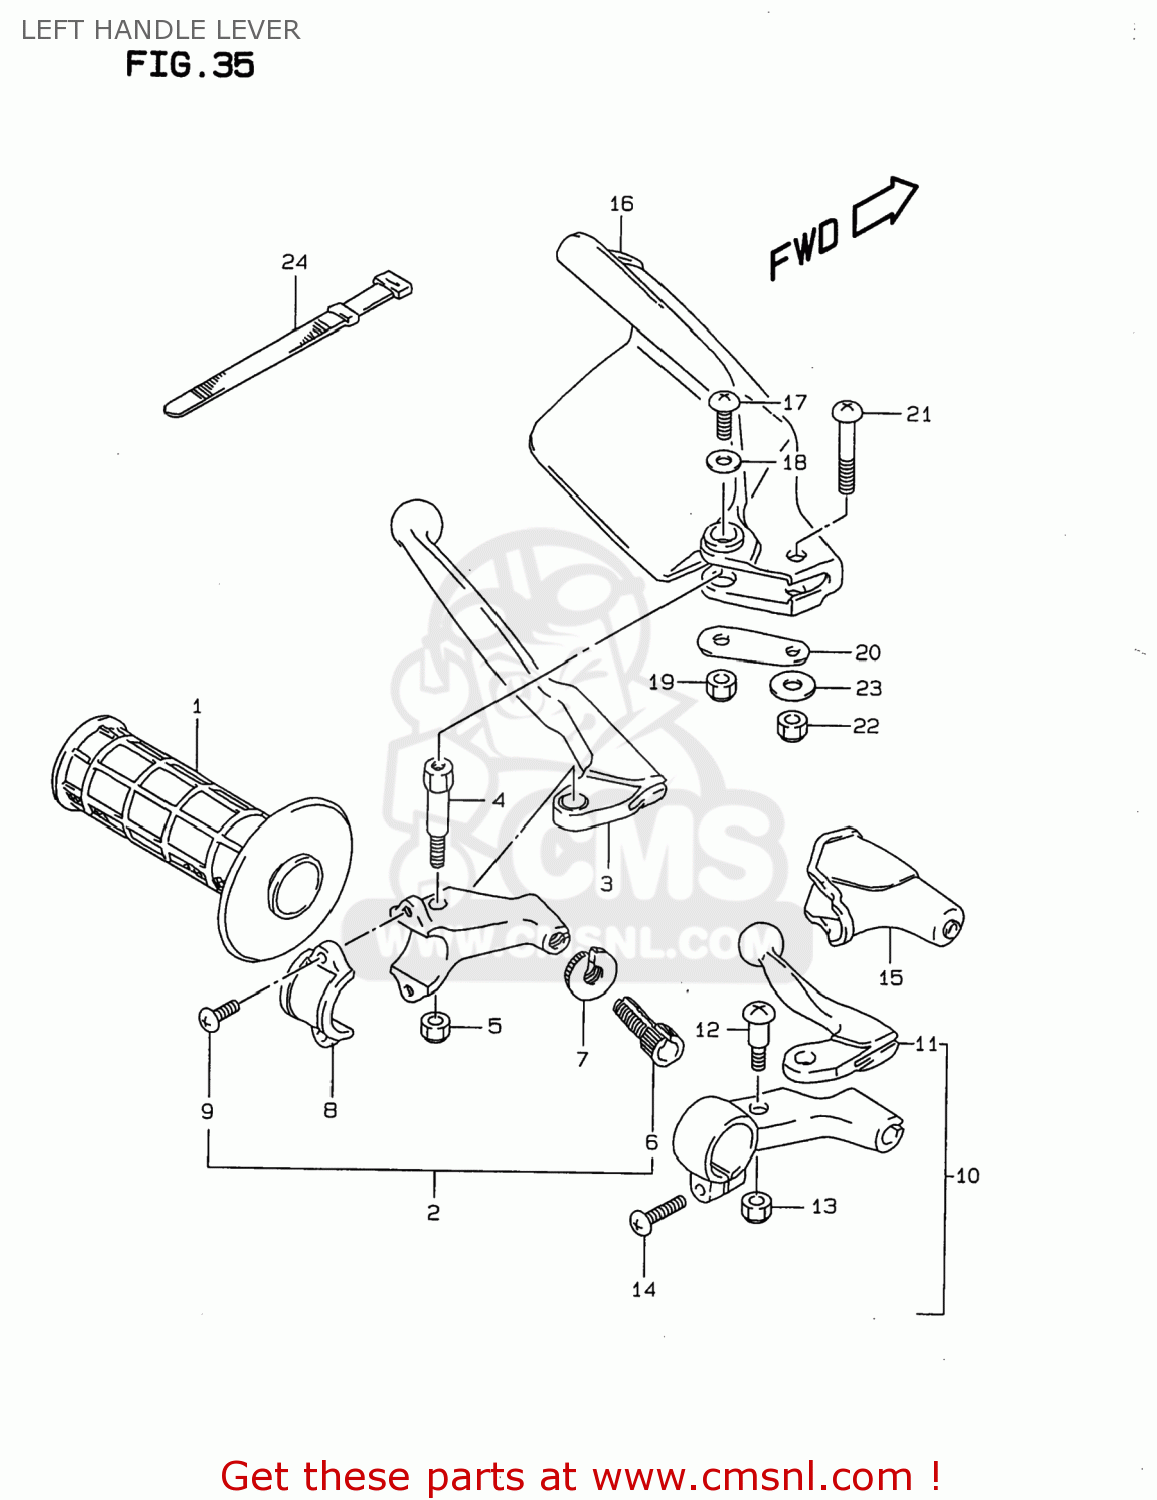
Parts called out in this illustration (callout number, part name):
1	GRIP,L
2	LEVER ASSY,CLUTCH
3	LEVER,CLUTCH
4	BOLT,LEVER SET
5	NUT 6MM
6	ADJUSTER,CABLE
7	NUT,LOCK
8	BRACKET,CLUTCH LEVER HOLDER
9	SCREW(5X14)
10	LEVER ASSEMBLY,DECOMPRESSION
11	LEVER,DECOMP
12	BOLT,LEVER PIVOT
13	NUT
14	SCREW, 6X20
15	COVER,DECOMP LEVER DUST
16	COVER,KNUCKLE,L
17	SCREW
18	WASHER(5.5X16X1.2)
19	NUT 6MM
20	PLATE,KNUCKLE COVER,L LWR
21	SCREW(6X35)
22	NUT 6MM
23	WASHER(6.5X16X1.6)
24	CLAMP(L:120)
